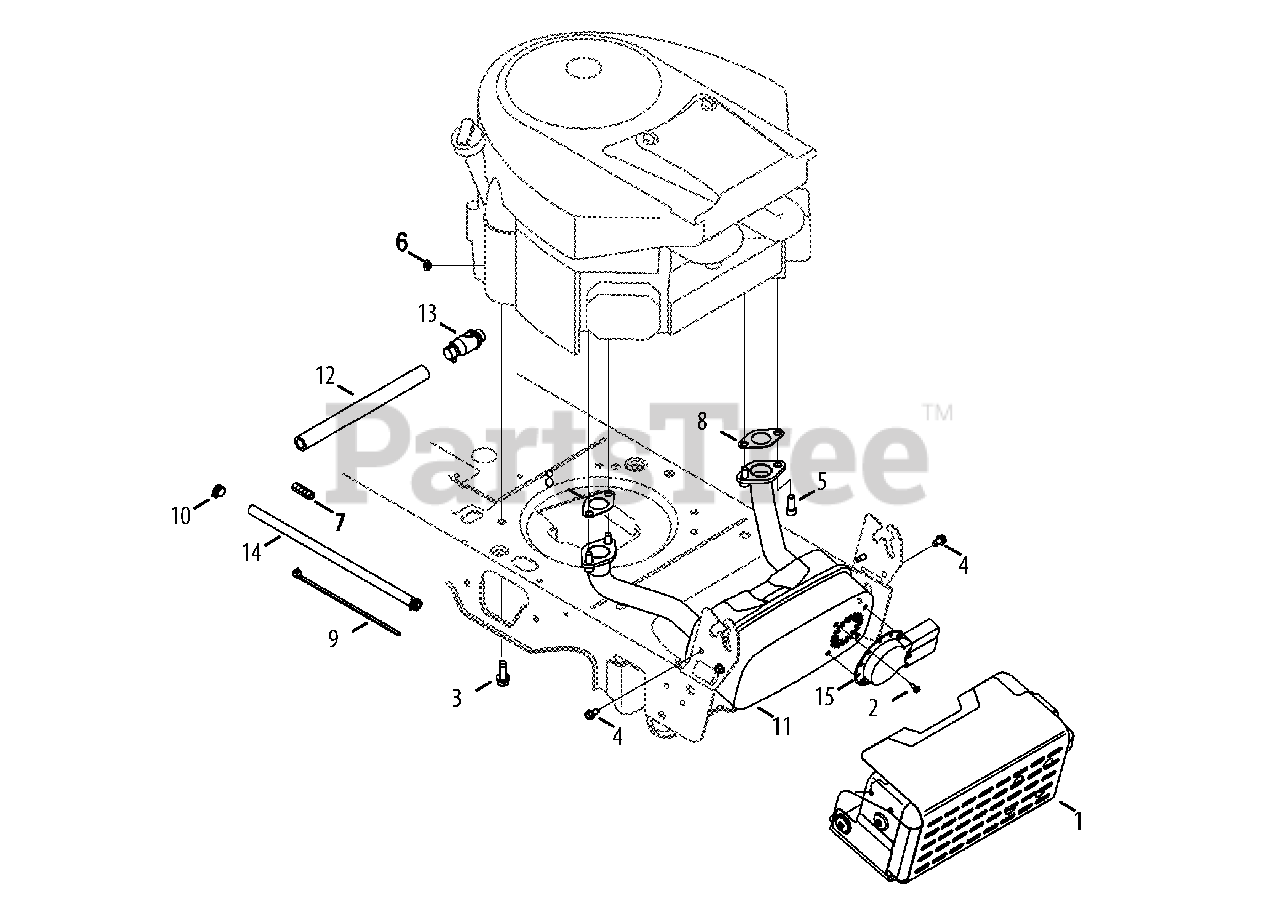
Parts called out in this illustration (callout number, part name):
1	Mulffler Shield Assembly
2	Screw, Indented Washer, #8-18:0.500
3	Taptite Screw, 3/8-16:1.000
4	Taptite Screw, 1/4-20:0.500
5	Socket Head Screw, 5/16-18:.750
6	Sems Nut, 1/4-20
7	Hose Vent
8	Exhaust Gasket
9	Cable Tie, 3/16 x .05 x 7.4
10	Hose Clamp, .490 DIA.
11	Muffler
12	Oil Drain Extension Hose
13	Oil Drain
14	Fuel Hose
15	Long Muffler Deflector, EPA
